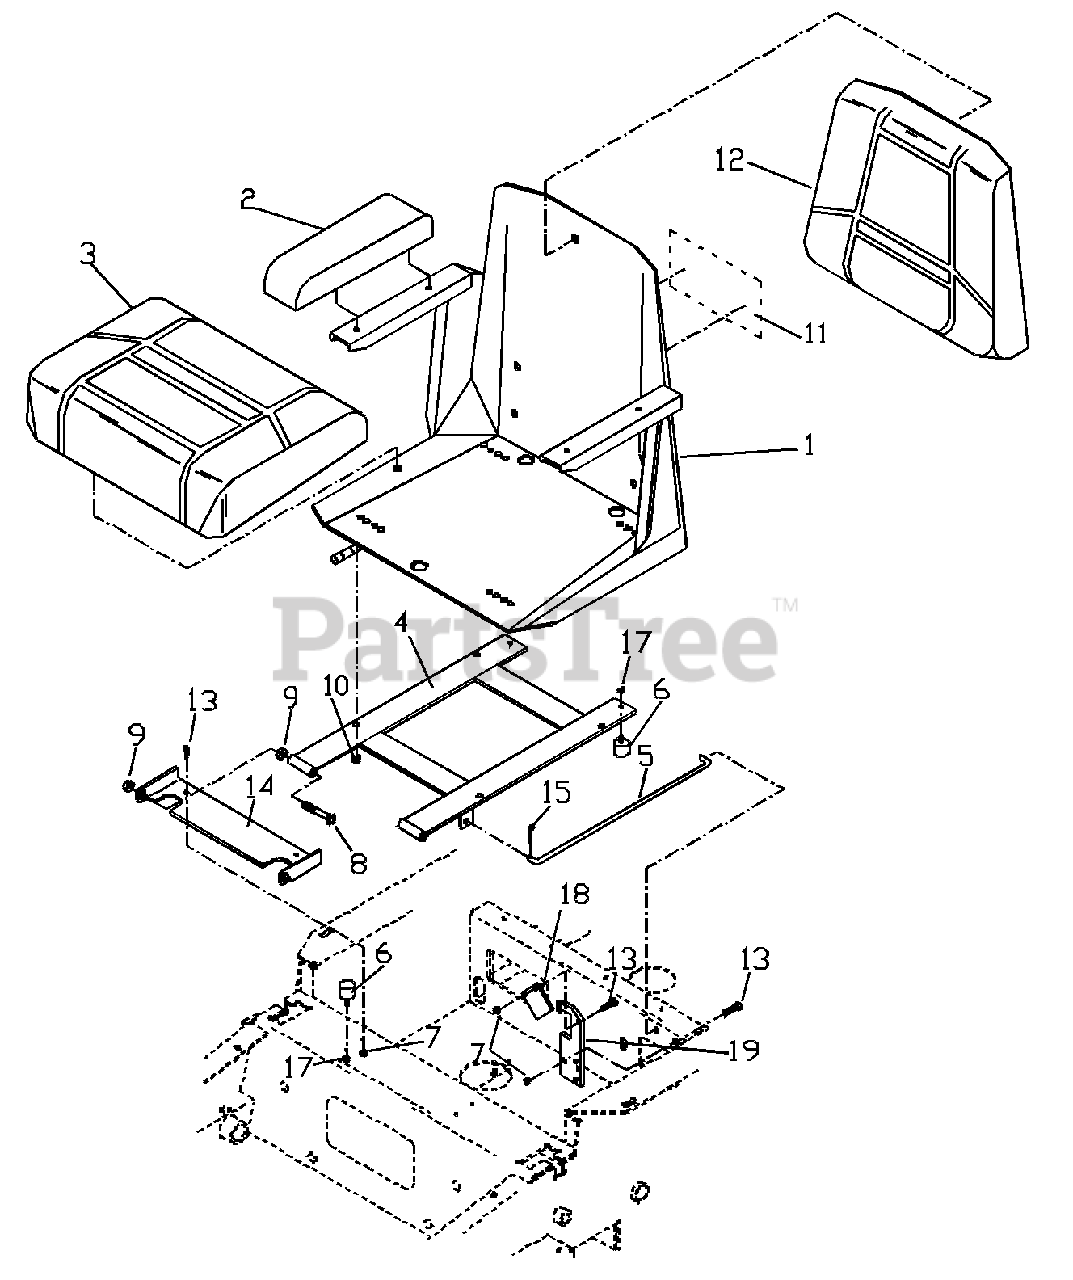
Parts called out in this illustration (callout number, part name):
1	SEAT COMPLETE
2	ARM REST CUSHIONS (1 PAIR)
3	SEAT CUSHION W/SWITCH
4	SEAT MOUNT
7	NUT 1/4 LOCK
8	HCS 3/8 X 3.0
9	NUT 3/8 LOCK
10	NUT 5/16 NYLOC
11	DECAL, CROWN
12	BACK CUSHION
13	HCS 1/4 X 3/4
14	SEAT BRACKET W/DECAL
15	COTTER PIN
17	NUT 1/4 NYLOC
18	SEAT LATCH
19	SEAT LATCH MOUNT
